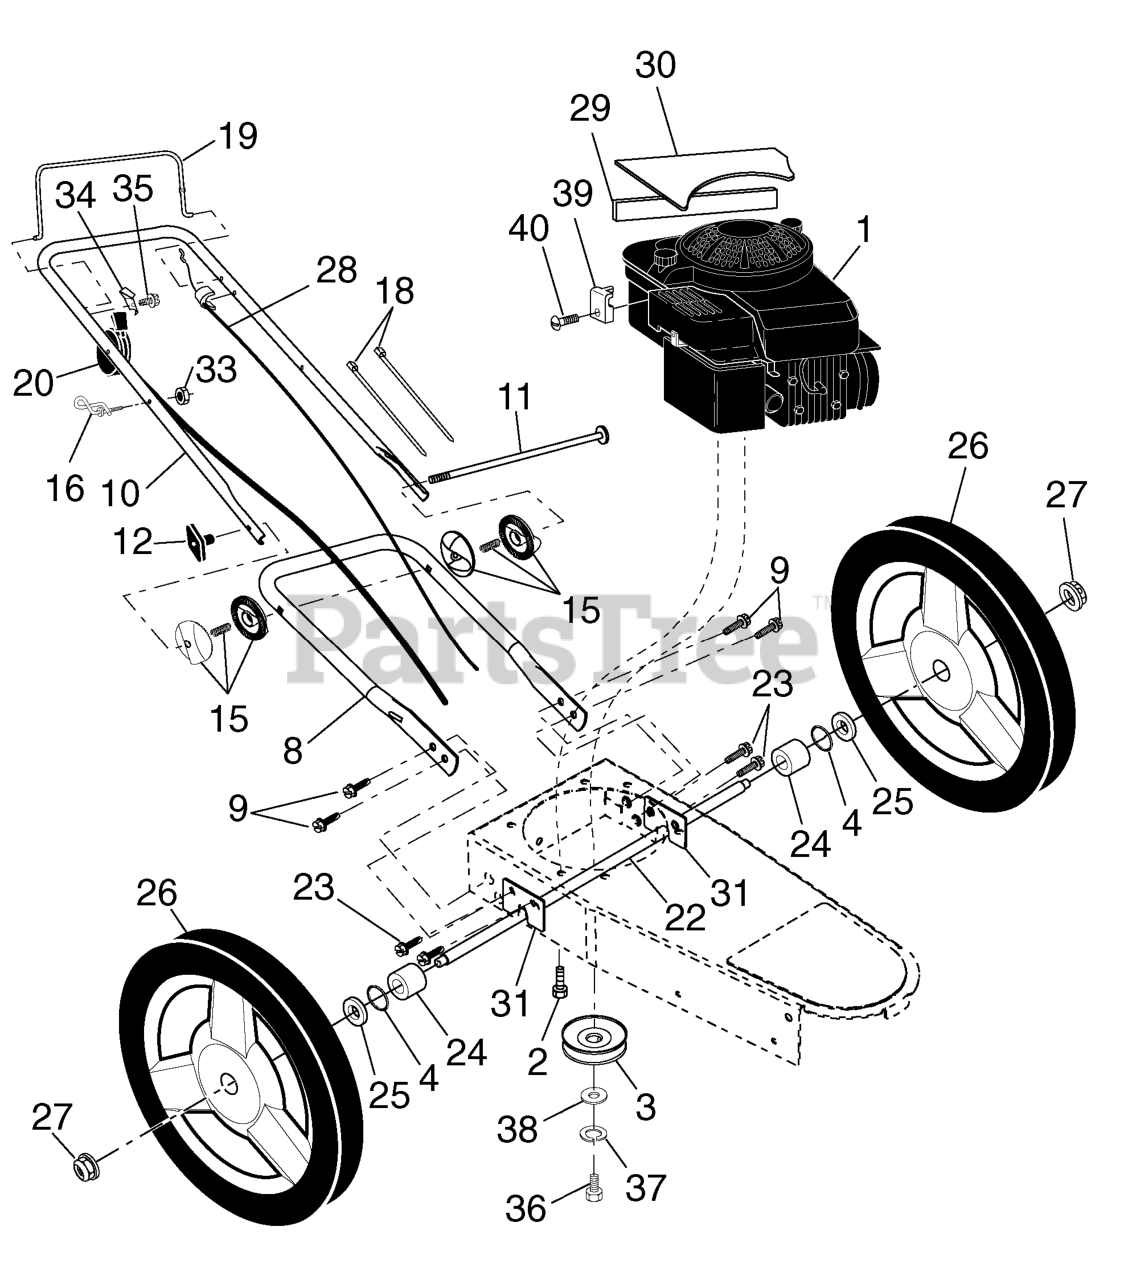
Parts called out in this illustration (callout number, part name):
2	BOLT 3/8-16X1-1/8
3	PULLEY, ENGINE
4	O-RING..070X.487.NEOPRENE
8	HANDLE.LOWER.STRG.TIMMER.BLACK
9	BOLT.HEX.HD.WASHER.5/16-18X.75
10	HANDLE.UPPER.STRG.TIMMER.BLACK
11	BOLT.HANDLE.WHEELED.TRIMMER
12	KNOB, DEFLECTOR
15	ADJSTR.ASSEM.HANDLE.WHLD.TRIMM
16	RB GUIDE.ROPE.STD.BLK.ZIN WSL
18	TIE GUIDE
19	BAIL.SPINDLE.ENGAGE.BLACK
20	RP CONTROL.THRO.S-TRM.SNPIN.BS
22	AXLE SHAFT ASSEMBLY
23	BOLT.HEX.HD.WASHER.5/16-18X.75
24	SPACER.AXLE.STRING.TRIMMER
25	WASHER.FLAT.1/2
26	WHEEL ASSY
27	NUT.HEX.FLANGE.3/8-16.LOCKNUT
28	CONTROL.DRIVE.TRIMMER.WHEELED
29	DECAL, WARNING
30	DECAL, WARNING
31	BRACKET, AXLE
33	NUT
34	BRACKET.UPSTOP.RT
36	SCREW, HEX HD 3/8-24 X 1-3/8
37	LOCKWASHER
38	WASHER,HARDEN
39	Clamp, Cable
40	SCREW.HEX.HEAD.WASHER.10-16
